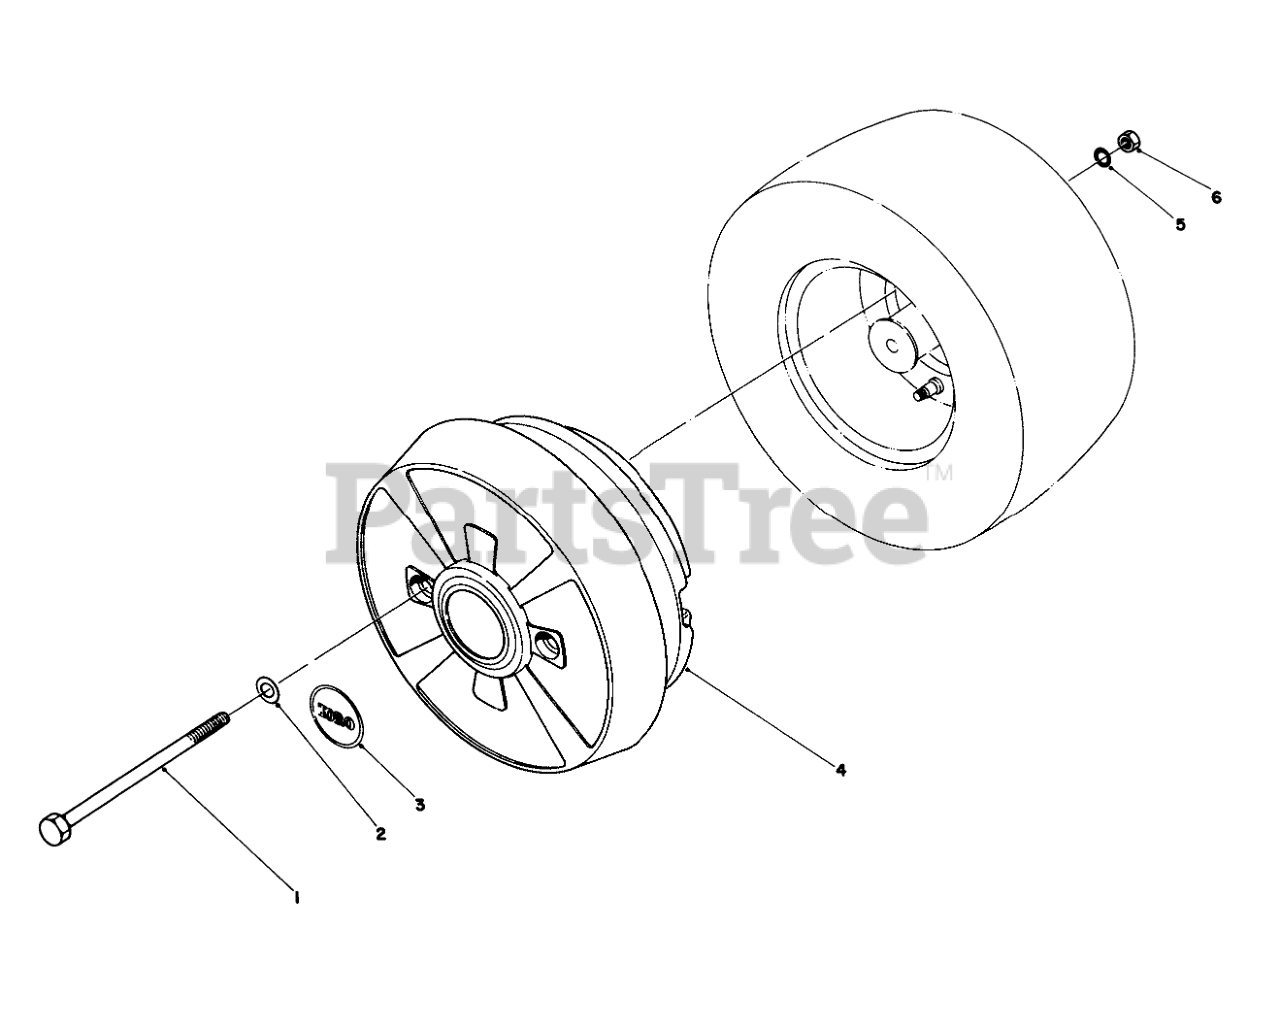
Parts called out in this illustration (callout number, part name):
1	SCREW-HH
2	WASHER-FLAT
3	Decal
4	Wheel Weight
5	NUT-HEX
6	NUT-LOCK, NI
